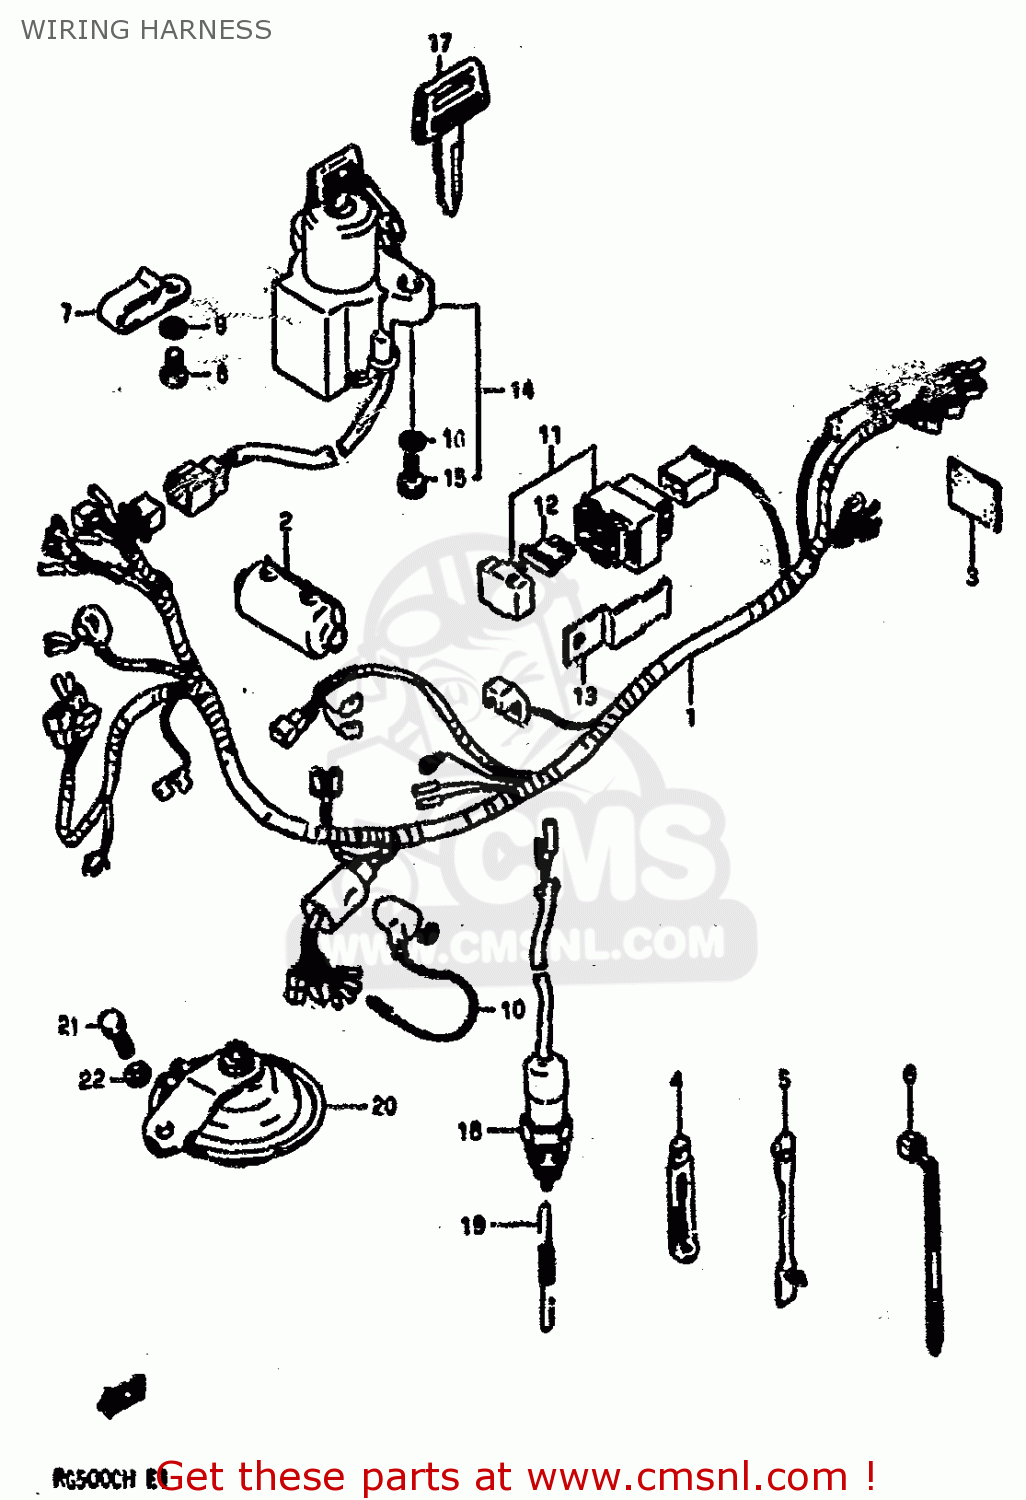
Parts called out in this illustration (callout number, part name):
1	HARNESS,WIRING
2	BOOT,WIRING HARNESS
3	COVER,HARNESS
4	CLAMP
5	CLAMP
6	CLAMP(L:95)
7	CLAMP,HANDLE SWITCH
8	SCREW
9	WASHER,LOCK
10	WIRE,WATER TEMPERATURE GAUGE
11	BOX ASSEMBLY,FUSE
12	FUSE(20A)
13	BRACKET,FUSE
14	LOCK ASSY
15	BOLT
16	WASHER,LOCK
17	KEY,BLANK
18	SWITCH ASSEMBLY,STOP LAMP
19	SPRING
20	HORN ASSY
21	BOLT
22	WASHER,LOCK
